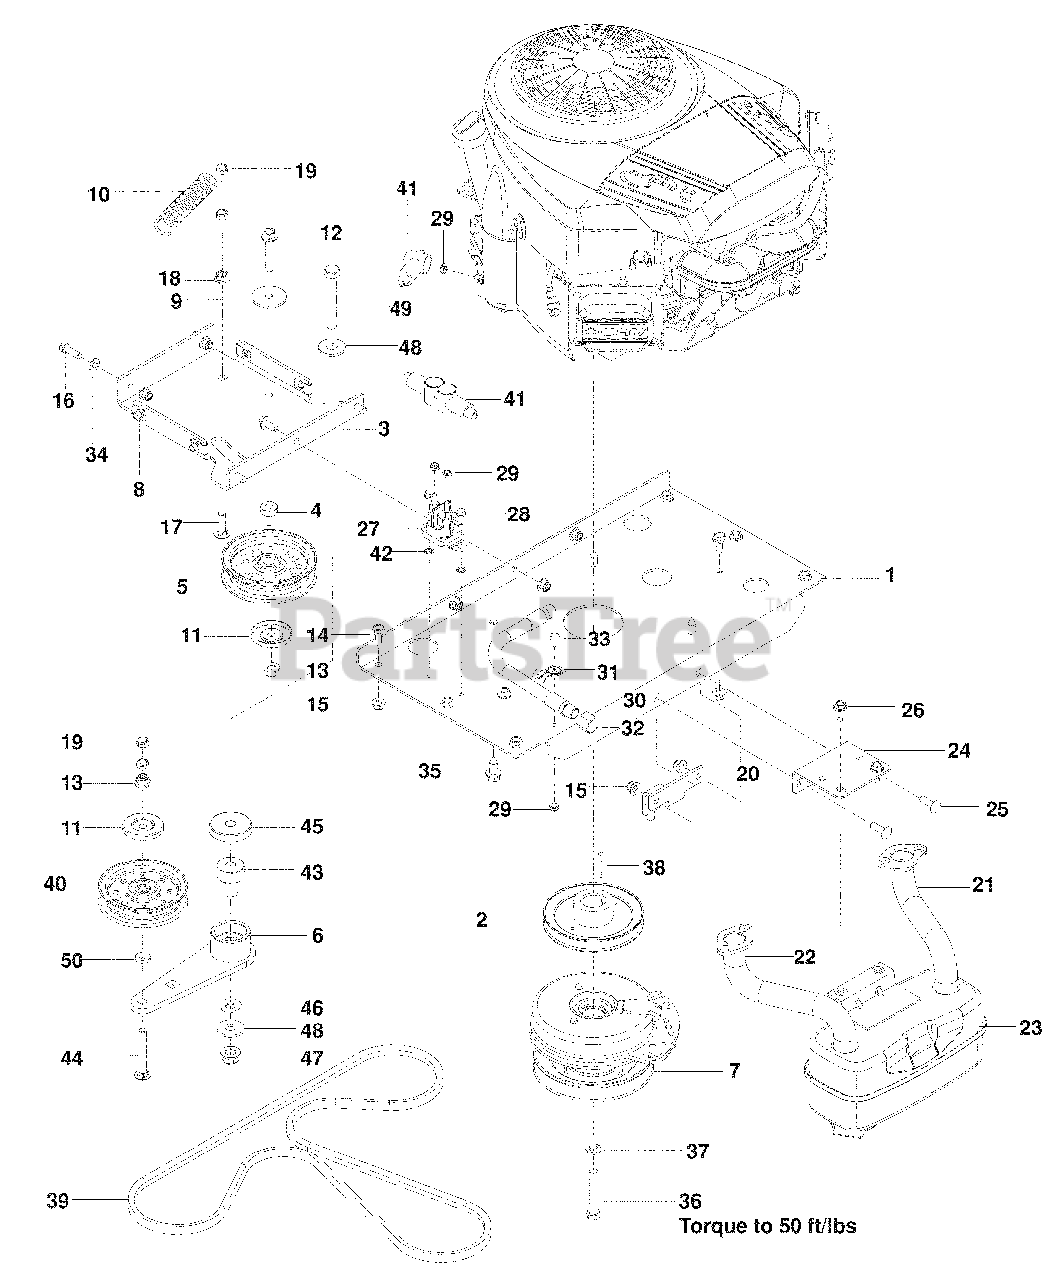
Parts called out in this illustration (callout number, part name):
1	PLATE, ENGINE w/ DECAL
2	PULLEY, V 11/8 BORE
3	PLATE, IDLER SUPPORT
4	PIVOT, IDLER
5	PULLEY, IDLER
6	ARM, IDLER w/ BEARINGS
7	CLUTCH, 200 FT-LB
8	RETAINER, U TYPE
9	WASHER, SPECIAL
10	SPRING, PUMP
11	SHIELD, DUST
12	HHFS 3/8-16 x 2
13	NUT 3/8-16 HEX FLG NYLOC
14	HHFS 5/16-18 x ¾
15	NUT 5/16-18 HEX FLG NYLOC
16	HCS 5/16-18 x 1
17	RHSNB 3/8-16 x 1¼
18	NUT 3/8-16 HEX WHIZLK
19	NUT 3/8-16 HEX JAM NYLOC
20	STOP, CLUTCH
21	EXHAUST TUBE, RT
22	EXHAUST TUBE, LT
23	MUFFLER ASM TWIN
24	BRKT, MUFFLER, BLK
25	RHSSNB 5/16-18 x 1
26	BOLT 5/16-18 x ¾ THD FRM
28	SCREW ¼-20 x 8 THD FRM
29	NUT ¼-20 HEX THIN NYLOC
30	HOSE-DRAIN
33	HCS ¼-20 x 2
34	WASHER 5/16 SAE FLAT
35	HHFS 3/8-16 x 1 THD FRM
36	HCS 7/16-20 x 2½
37	WASHER 7/16 SLW
38	KEY ¼ SQ x 1¼
40	PULLEY, IDLER SECONDARY
42	WASHER ¼ INT TOOTH LK
43	PIVOT, BEARING
44	RHSNB 3/8-16 x 2¾
45	SHIELD, DUST
46	WASHER ½" BELLEVILLE
47	NUT ½-13 HEX FLG NYLOC
48	WASHER ½ FLAT ZD
49	HCS ½-13 x 3¼
50	WASHER 3/8 x ¾
